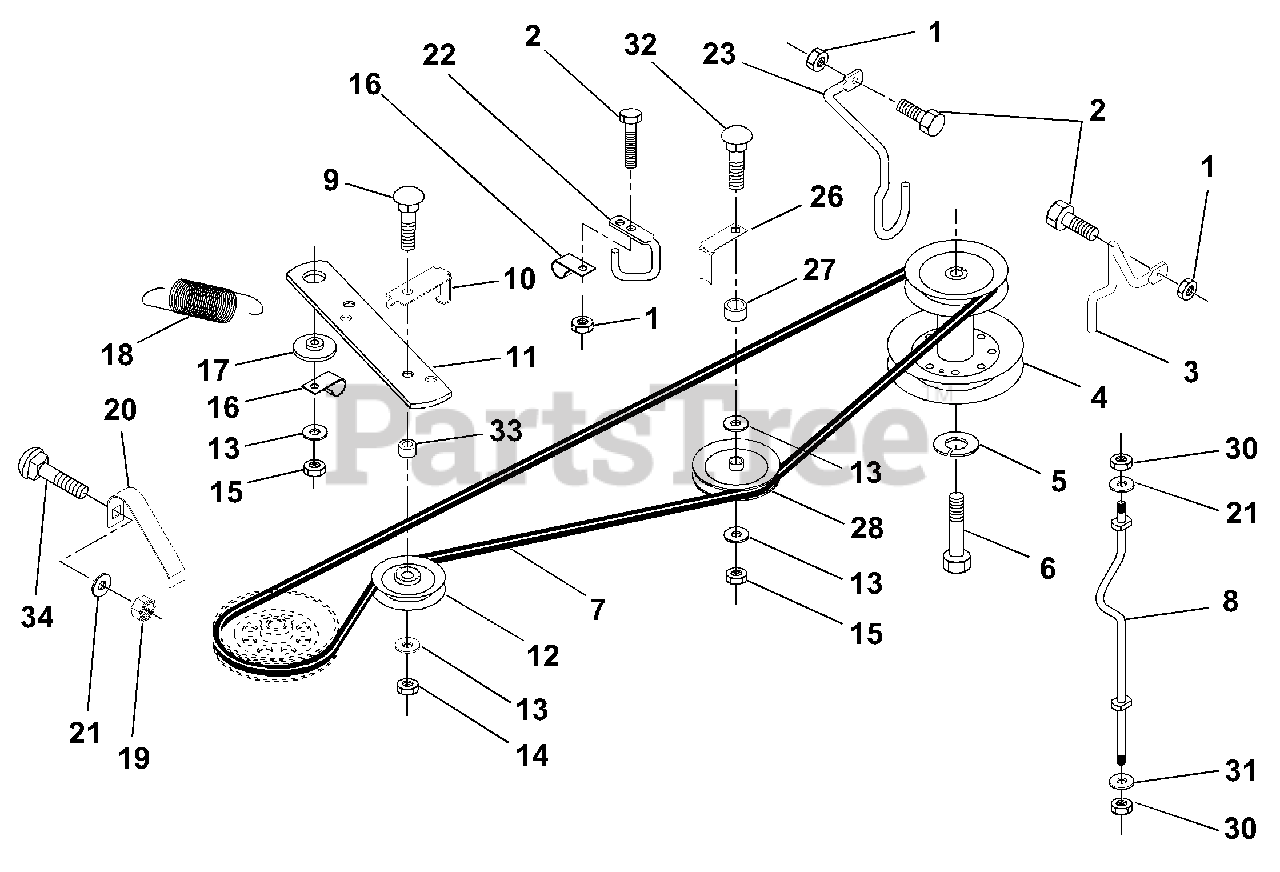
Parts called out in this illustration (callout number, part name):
1	Nut, Lock Hx w/Ins 5/16-18
2	Bolt, Hex Head 5/16-18 x 3/4
3	Keeper, Belt RH Front
4	Pulley, Engine
5	Washer, Lock 7/16
6	Bolt, Hex Fin M10 x 1.5 x 75mm
8	Keeper, Belt RH
9	Bolt, RDHD SQ 3/8-16 x 2-1/4
10	Keeper,Belt, Idler Pulley
11	Arm, Idler
12	Idler, Flat
13	Washer 13/32 x 13/16 x 16 Gauge
14	Nut, Centerlock 3/8-16
15	Nut, Hex, Lock Hex w/wsh 3/8-16
16	Clip Insulator
17	Spacer, Retainer
18	Spring, Extension
20	Keeper,Belt LH
21	Washer Nut Lock Hex w/Ins. 5/6-18
22	Keeper Frame Ground Drive Belt
23	Keeper,Belt LH Front
26	Keeper, Belt
28	Pulley, V-Idler
30	Nut Lock Hex w/Ins. 5/16-18
31	Washer 11/32 x 3/4 x 16 Ga.
32	Carriage Bolt
34	Carriage Bolt
